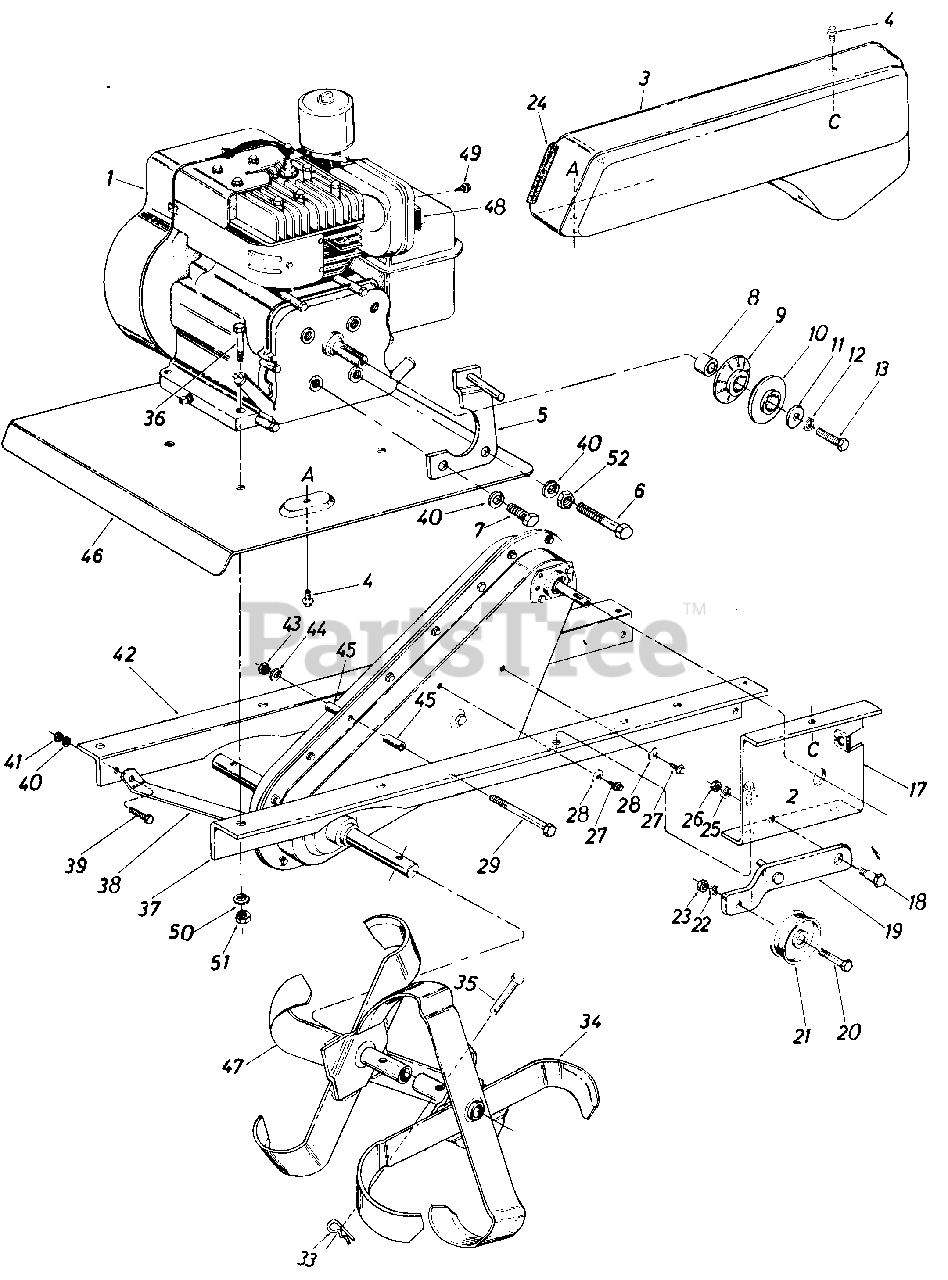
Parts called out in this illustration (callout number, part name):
1	Engine
2	Hex Wash. Hd. Self-Tap Scr. 5/16-24 x .50" Lg.
3	Belt Cover
4	Hex Wash. Hd. Self-Tap Scr. 1/4-20 x .50" Lg.
5	Belt Keeper Brkt. Ass'y.
6	Hex Bolt 5/16-24 x 2.25" Lg. (Grade 5)
7	Hex Bolt 5/16-24 x .62" Lg. (Grade 5)
8	Spacer
9	Pulley Half
10	Pulley Half
11	Fl-Wash. 3/8" I.D. x 1.25" O.D. x .100
12	L-Wash. 818n I.D.
13	Hex Scr. 3/8-24 x 1.00" Lg.
17	Idler Mounting Brkt.
18	Shld. Bolt
19	Idler Bracket Ass'y.
20	Hex Scr. 3/8-16 x 1.50" Lg.
21	Idler Pulley
22	L-Wash. 3/8" I.D.*
23	Hex Jam Nut 3/8-16 Thd.
24	Trim Strip-3"
25	L-Wash. 3/8" I.D.
26	Hex Jam Nut 3/8-16 Thd.
27	Hex Wash. Hd. Self-Tap Scr. 1/4 -20 x .50" Lg .
28	Belleville Wash. .26 I.D. x .75 O.D. x .060
29	Hex Scr. 5/16-18 x 2.75" Lg.
33	Hairpin Cotter
34	See Tine Chart Below
36	Bolt 5/16-18 x 1.5" Lg.
37	Frame Rail-L.H.
38	Front Brace Brkt.
39	Hex Scr. 5/16-18 x .75" Lg.
40	L-Wash. 5/16" I.D.
41	Hex Cent. L-Nut 5/16-18 Thd.
42	Frame Rail-R.H.
43	Hex Cent. L-Nut 5/16-18 Thd.
44	L-Wash. 5/16 I.D.
45	Spacer
46	Tine Shield
47	See Tine Chart Below
49	Hex Self-Tap Scr. #8-32 x.38" Lg.
50	L-Wash. 5/16" I.D.
51	Hex Nut 5/16-18 Thd.
52	Hex Nut 5/16-24 Thd.
